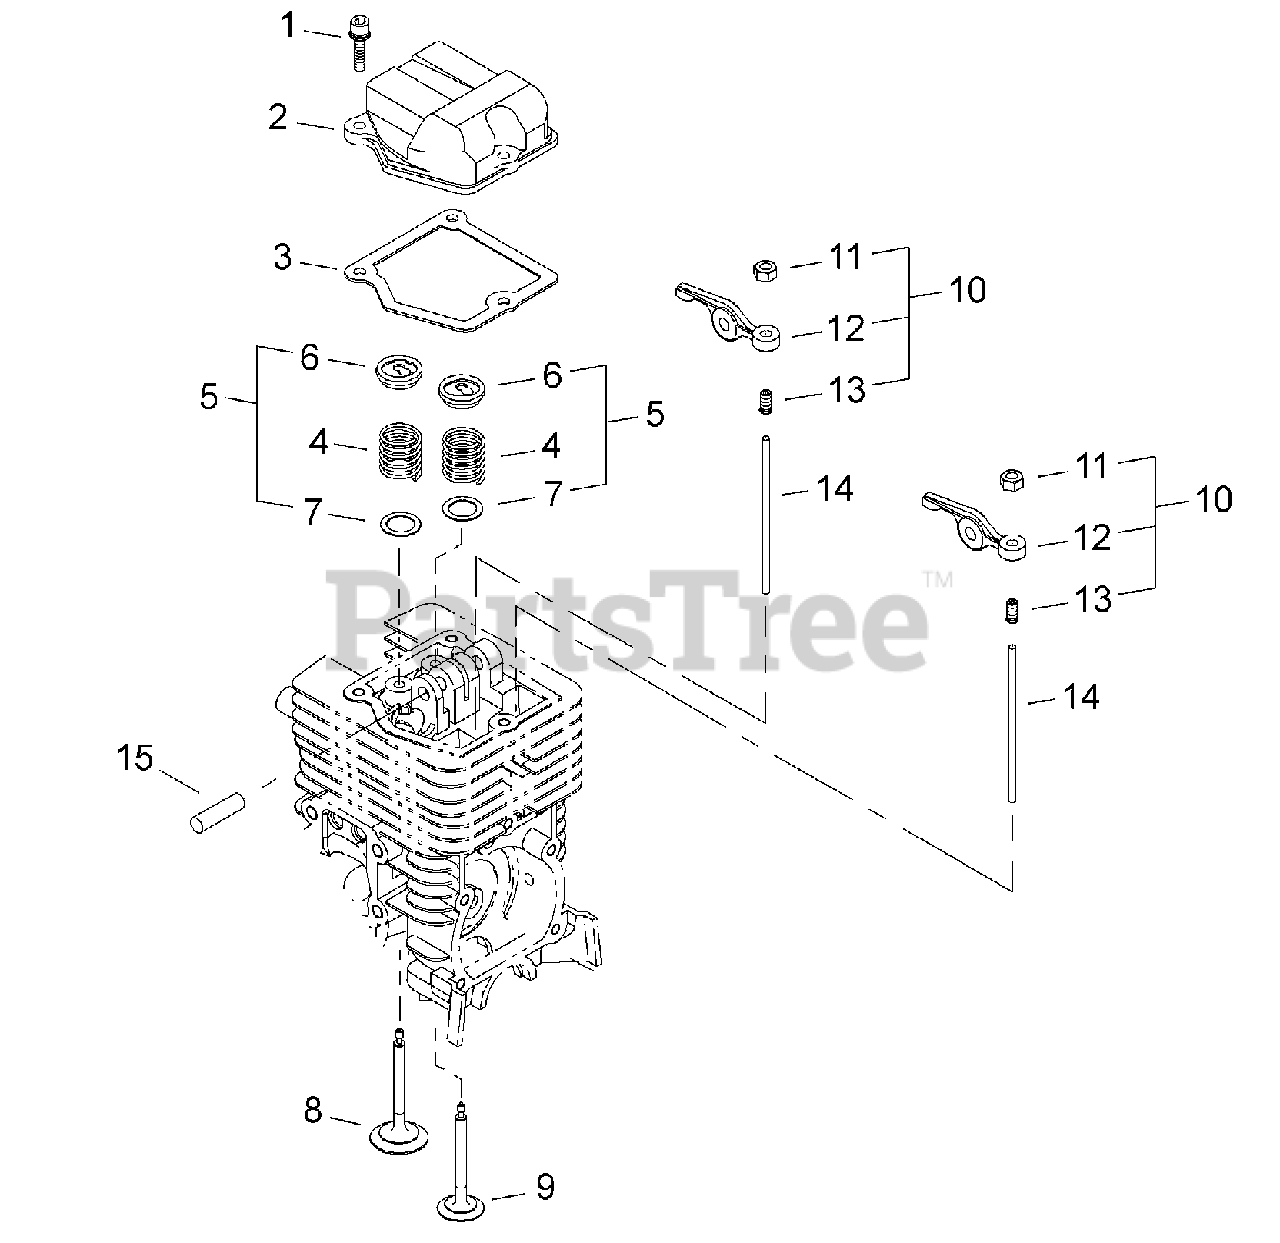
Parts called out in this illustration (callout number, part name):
1	SCREW - 4X12
2	COVER, ROCKER ARM
3	GASKET
4	SPRING, VALVE
5	VALVE RETAINER ASSY
6	RETAINER, VALVE
7	WASHER, VALVE - 9
8	VALVE, INTAKE
9	VALVE, EXHAUST
10	ROCKER ARM ASSY
11	LOCKNUT, ADJUSTER
12	ARM, ROCKER
13	SCREW, ADJUST
14	PUSHROD
15	SHAFT, ROCKER ARM - 5X31.8
